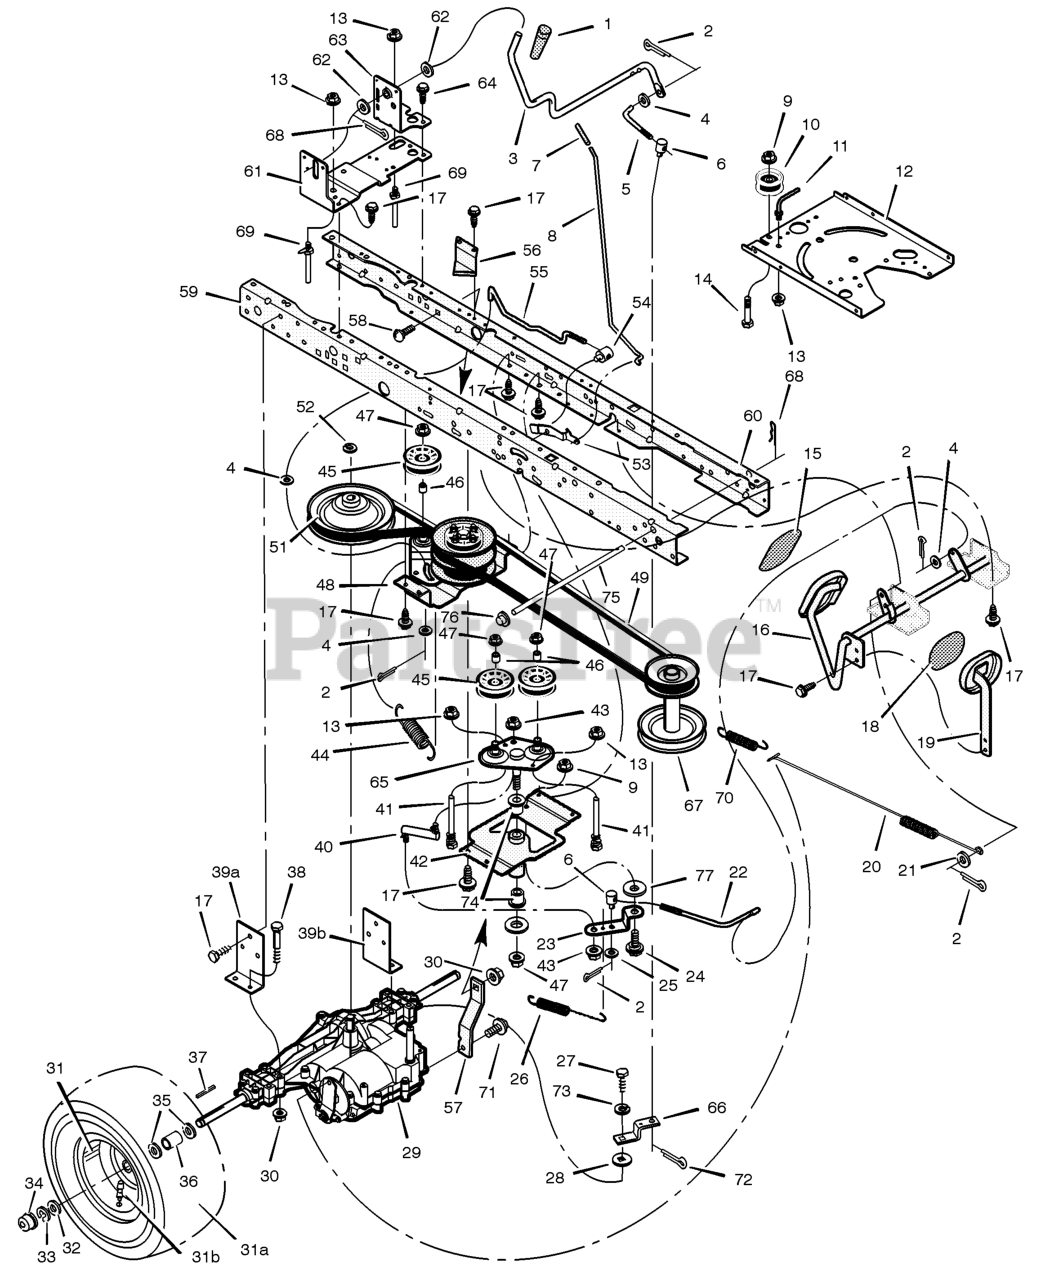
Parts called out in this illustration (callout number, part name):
1	Grip
2	Pin, Cotter
3	Lever, Shift
4	Washer
5	Link, Shifter
6	Nut, Adjuster
8	Rod, Parking Brake
9	Nut
10	Pulley, Idler
11	Guide, Belt
12	Plate, Steering
13	Nut
14	Bolt, Hex
15	Pad, Motion Drive
16	Assembly, Speed Control
17	Screw, Self Tapping
18	Pad, Brake Pedal
19	Assembly, Brake Pedal
20	Spring, Extension
21	Washer
22	Rod, Speed Control
23	Bellcrank
24	Bolt, Shoulder
26	Spring, Extension
27	Screw, Cap
29	Transaxle
30	Nut
31	Assembly, Wheel and Tire
31B	Stem, Valve
36	Spacer
37	Key, Square
38	Bolt, Hex
39A	Bracket, Right Transaxle
39B	Bracket, Left Transaxle
40	Rod, Secondary Control
41	Guide, Belt
42	Bracket, Front Frame
43	Nut, Lock
44	Spring, Extension
47	Nut
48	Assembly, Variator and Idler
49	Belt, Primary
50	Belt, Secondary
51	Pulley, Transaxle
52	Ring, Snap
53	Latch, Parking Brake
54	Nut, Adjusting
55	Rod, Clutch
56	Bracket, Brake
57	BRACKET, Torque Strap, LH
58	Screw
59	Rail, Right Frame
60	Rail, Left Frame
61	Bracket, Right Shift
62	Washer
63	Bracket, Shift Pivot
65	Assembly, Idler
66	Yoke, Shift
67	Pulley, Stack
68	Pin, Hair
69	Guide, Belt
70	Spring, Return
72	Pin, Hair
75	Rod, Belt Guide
76	Nut, Push-On
